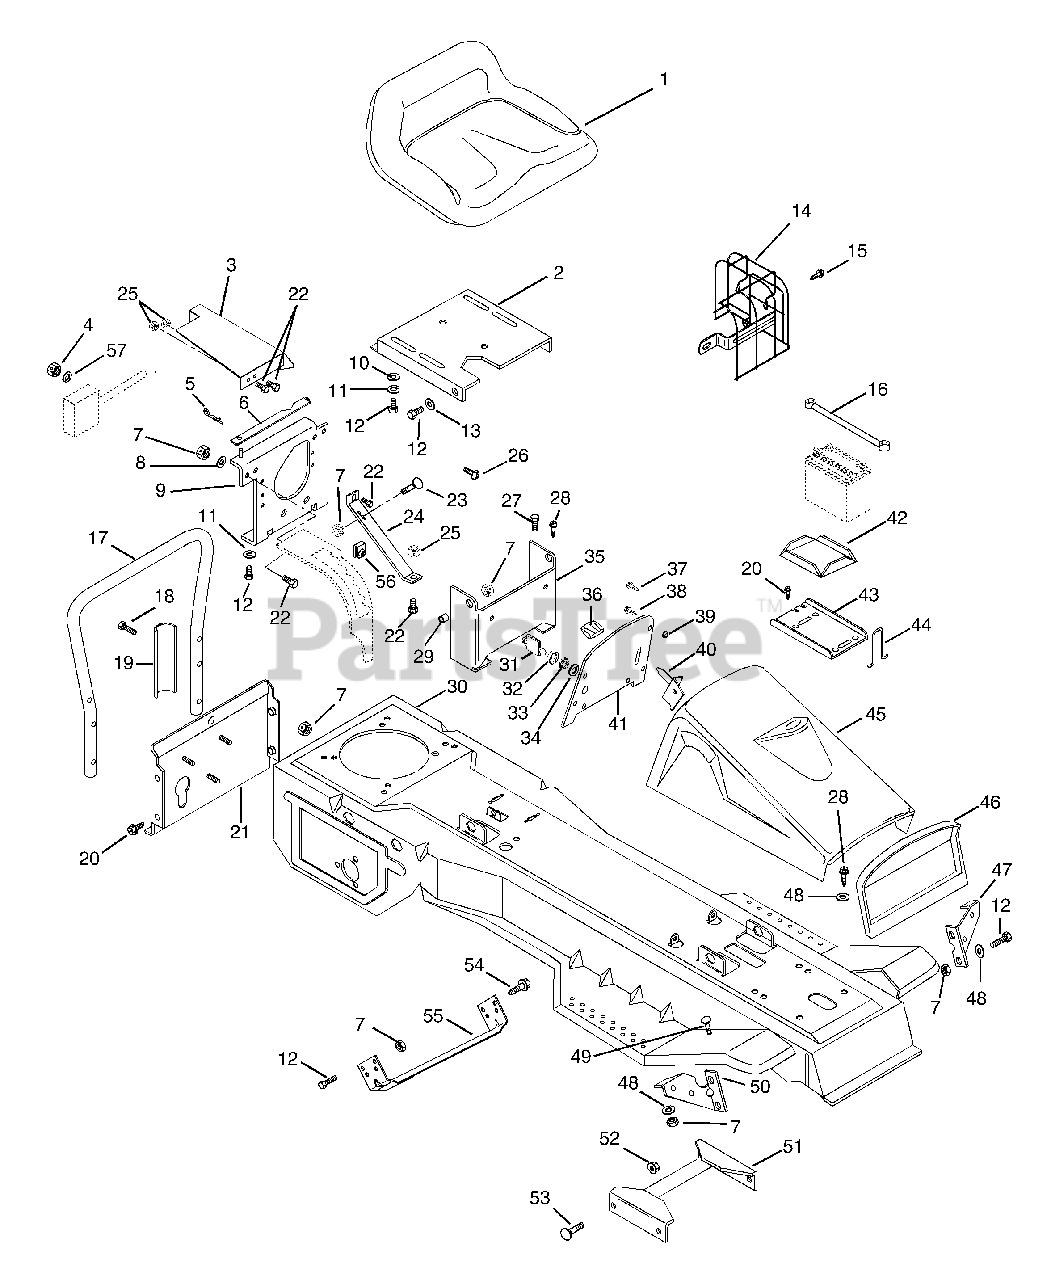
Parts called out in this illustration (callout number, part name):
1	SEAT- V1400
1	SEAT V-1300 LOW WELTLESS
2	SEAT BRACKET
3	BAFFLE
4	@NUT-HEX 10-24 YWZC
5	PIN-HAIR-INT .09X.188X2.00YWZC
6	SEAT HOLD DOWN
7	@NUT-LK-CTR .31-18 YWZC
8	WSHR-LK-INT .313X.030 PL
9	SEAT LEG ASSEMBLY
10	@WSHR-FL-STL.38X.875X.083 YWZC
11	WSHR-LK .312X.097 HVY YWZC
12	@BLT-HEX .31-18X.75 GR5 YWZC
13	WSHR-FL-STL .328X.875X.062YWZC
14	MUFFLER GUARD (B&S#495945)
15	SCREW (B&S#094887)
16	BATTERY STRAP
17	TUBE
18	@BLT-HEX .31-18X1.50 GR5 YWZC
19	BRACE
20	@SCR-TAP .31-18X.50 HWH TR YWZ
21	BACK COVER
22	@BLT-HEX .25-20X.50 GR5 YWZC
23	@BLT-RHDSSQNK .31-18X.62 G5YZ
25	@NUT-LK-CTR .25-20 YWZC
26	@SCR-MCH 10-24X.75 HWH YWZC
27	@BLT-HEX .31-18X.50 GR5 YWZC
28	@SCR-TAP .25-20X.50 HWH TR YWZ
29	SPACER BUSHING .5 X .32 X .163
30	FRAME WITH DECALS
31	KEY SET
32	CAP - IGNITION SWITCH
33	NUT-PANEL .625-32 GRECO
34	WSHR-LK-INT .625X.045 YWZC
35	SEAT PIVOT BRACKET
37	SCR-TAP 10-12X.50 CRPH PL A BL
38	SCR-TAP 10-24X.375 TORX PHD YZ
39	PLASTIC GROMMET
40	THROTTLE CONTROL
41	DASH PANEL
42	RUBBER PAD
43	BATTERY TRAY
46	GRILLE INSERT & SHELL ASSEMBLY
47	L H FENDER BRACE
48	WSHR-FL-STL .323X.625X.062 YWZ
49	@BLT-RDHDSQNK .31-18X.75 G5YZ
50	RH FENDER BRACE
51	FRAME BRACE
52	@NUT-SPNLK-FLG .312-18 YWZC
53	@BLT-RHDSSQNK .31-18X.62 G5YZ
54	@SCR-TAP .31-18X1.50 HWH TR YZ
55	FRAME BRACE
56	NUT RETNR .25-20
57	@WSHR-LK-EXT.200X.402X.022YWZC
